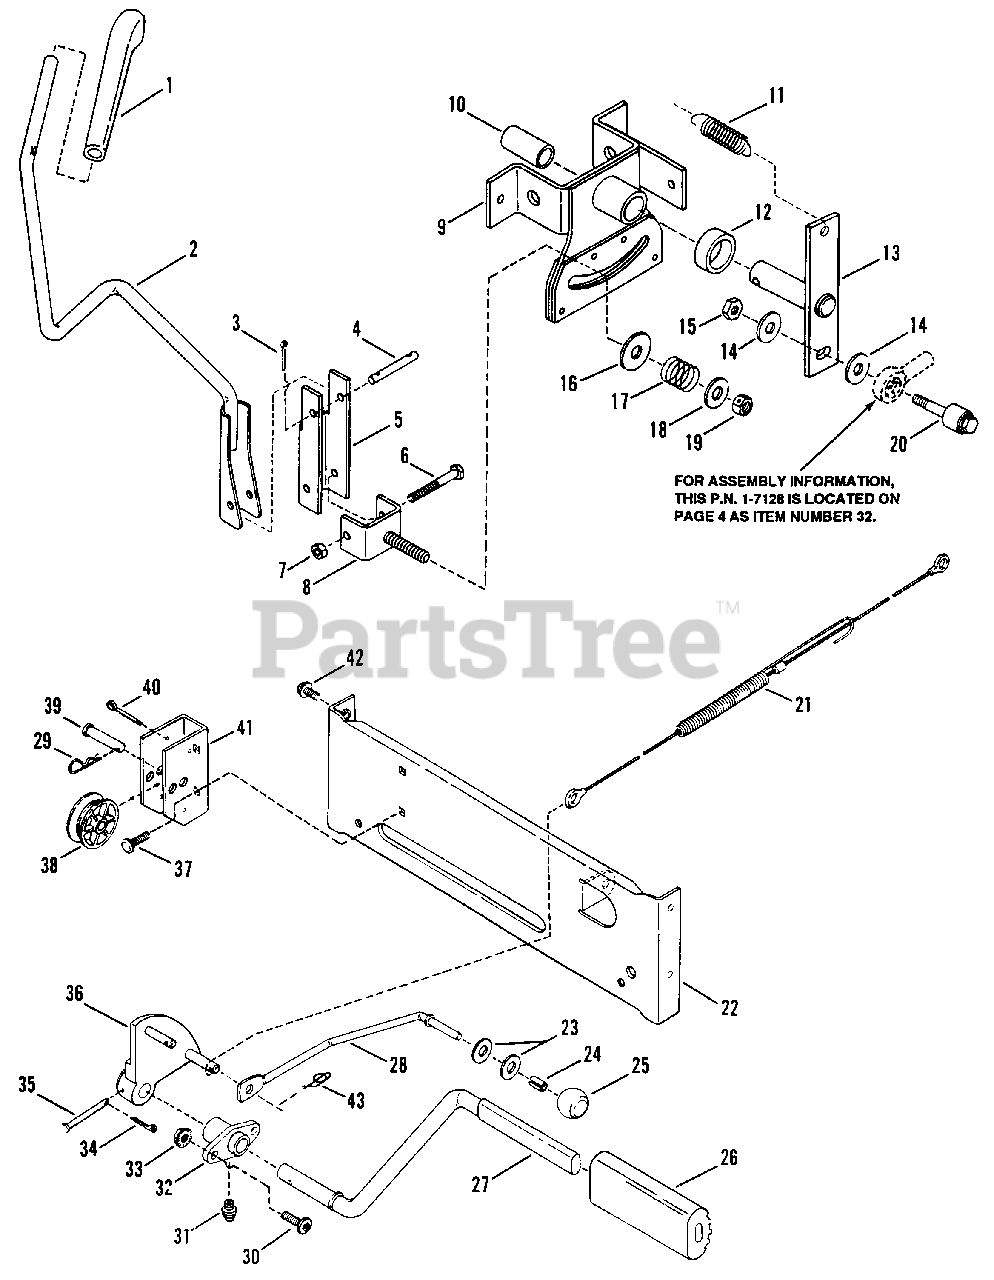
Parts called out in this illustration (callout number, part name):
1	KNOB, Shifter (Elongated)
2	SHIFTER, Transmission
3	COTTER-PIN, 3/32 x 3/4"
4	PIN, Shifter
5	EXTENSION, Hub
6	SCREW, 1/4-28 x 2" Hex Head Cap
7	NUT, 1/4-28 Hex Lock
8	RUB PLATE ASSEMBLY
9	SHIFT PIVOT ASSEMBLY
10	BEARING, Shift Pivot Assembly (No longer available, try using 7015048)
11	SPRING, Shift
12	SPACER, 1.0 OD x .755 ID x .310 L
13	SPEED CONTROL
14	WASHER, 5/16 Flat
15	NUT, 5/16-24 Hex
16	WASHER, Special
17	SPRING, Tension
18	WASHER, 3/8" Flat
19	NUT, 3/8-24 Hex Lock
20	CAM FOLLOWER
21	CABLE, Clutch (22.5" Long)
22	BRACE
23	WASHER, Nylon 5/16"
24	RING, Tolerance 5/16" x 1/2"
25	KNOB, Latch 5/16"
26	PAD, Pedal
27	PEDAL, Clutch/Brake
28	LATCH, Clutch/Brake
29	PIN, Hair 1.12"
30	SCREW, 5/16-18 x 7/8" Torx
31	FITTING, Lube 3/16"
32	PIVOT, Clutch/Brake Pedal
33	NUT, 5/16-18 Hex Lock
34	COTTER-PIN, 1/16 x 3/4"
35	PIN, Clevis, 3/16 x 1 1/2"
36	BRAKE ARM
37	BOLT, 1/4-20 x 3/4" Short Neck Carriage
38	SPOOL, Bracket
39	PIN, Clevis, 3/8 x 1 9/32"
40	COTTER-PIN, 1/8 x 1 1/4"
41	BRACKET, Spool (No longer available, try modifying 7033328 to fit)
42	SCREW, 5/16-18 x 1/2" Self-Tapping
43	COTTER-PIN, 3/8 Self-Lock
